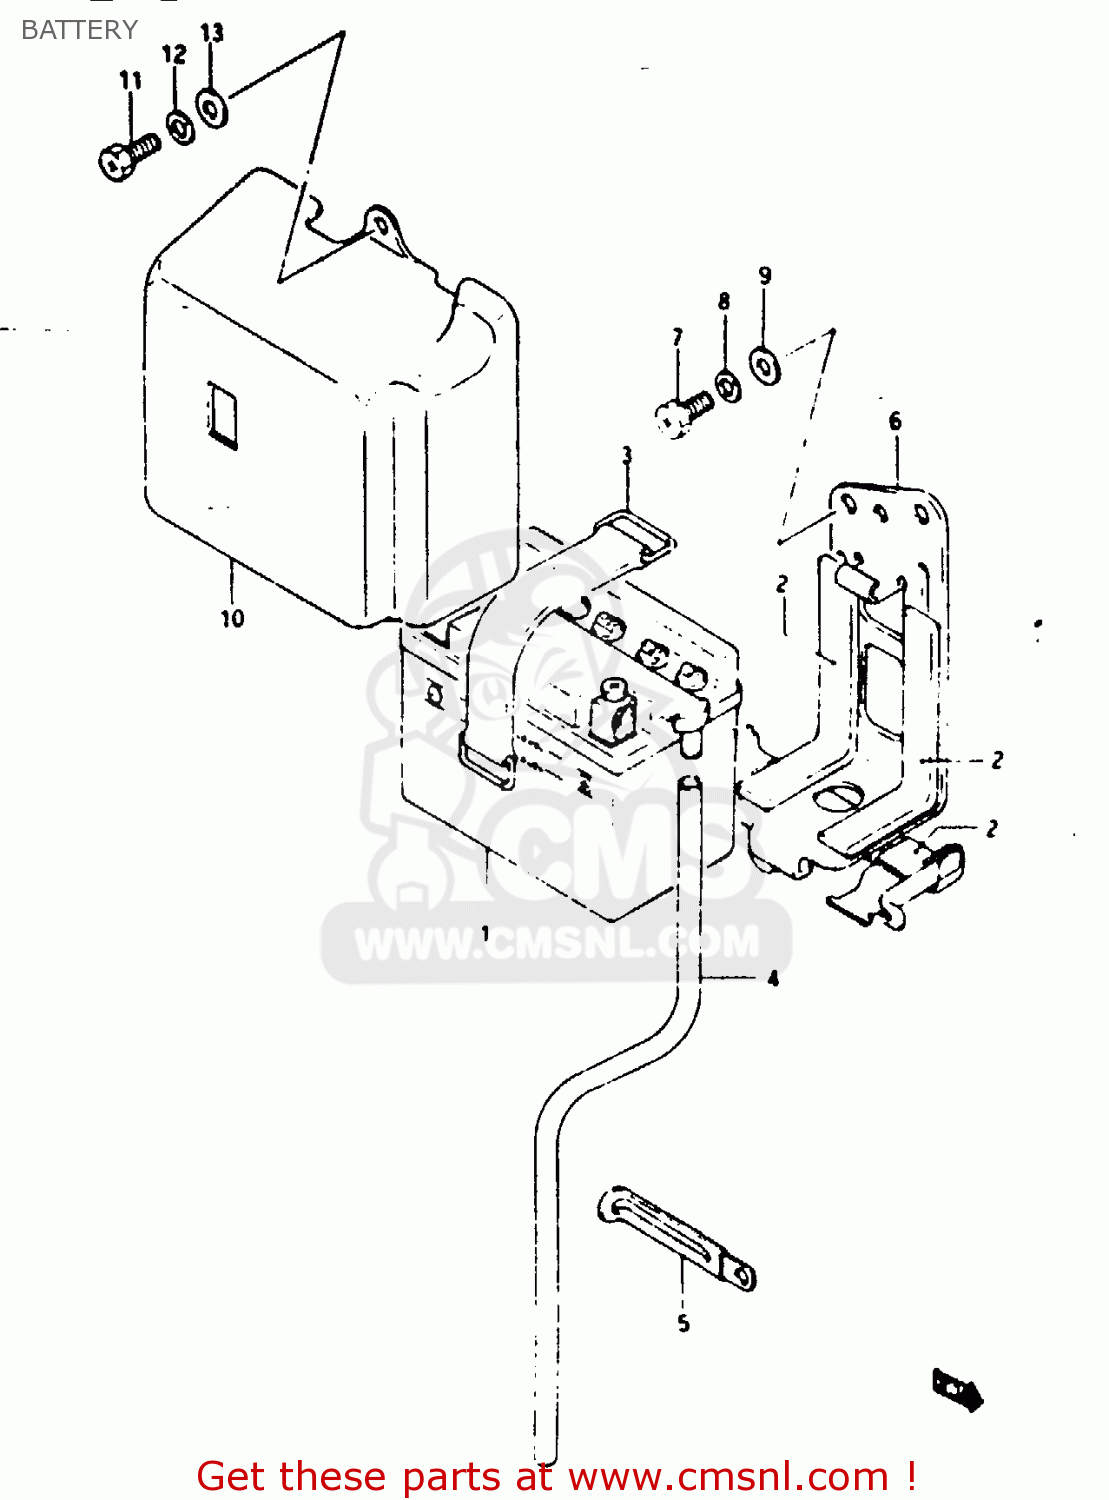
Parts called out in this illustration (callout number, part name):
1	BATTERY ASSY(YB4L-B,12V4.2AH)
2	PROTECTOR,BATTERY
3	BAND
4	HOSE,BATTERY EXHAUST
5	CLAMP
6	HOLDER,BATTERY
7	SCREW
8	WASHER,LOCK
9	WASHER
10	COVER, BATTERY
11	SCREW
12	WASHER,LOCK
13	WASHER
